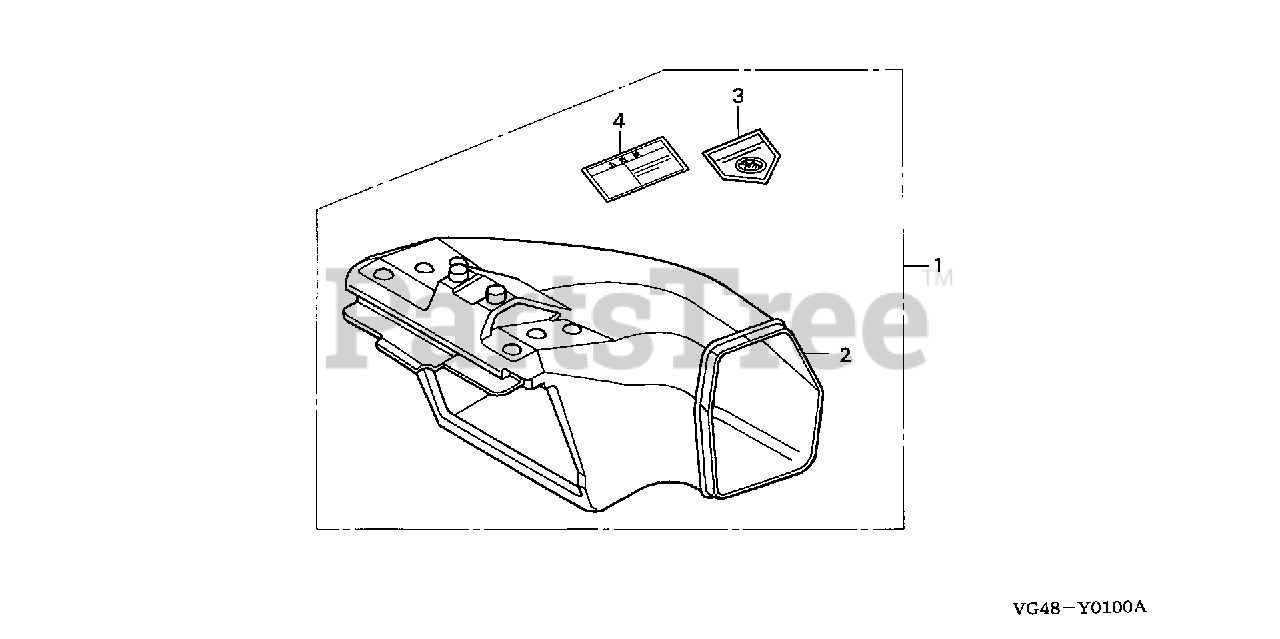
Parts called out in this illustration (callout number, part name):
1	CHUTE KIT, SIDE DISCHARGE
2	CHUTE KIT, SIDE DISCHARGE
3	CAUTION C, HOUSING
